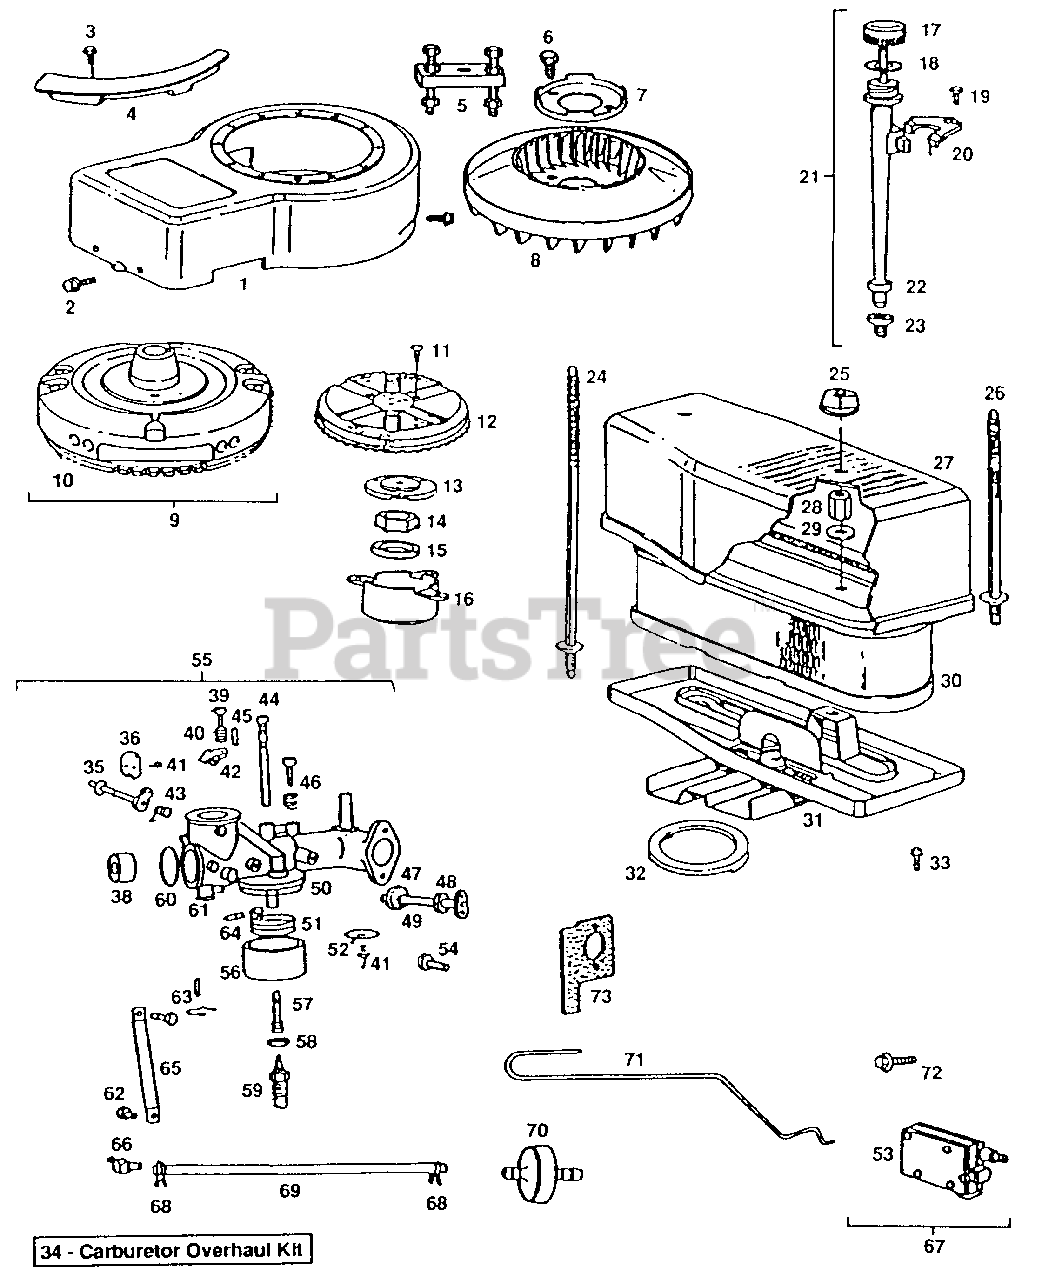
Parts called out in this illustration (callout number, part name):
1	Housing, Blower
2	Screw, Blower Housing Mounting Sem
3	Screw, Hex Hd.
4	Guard. Flywheel
5	Puller, Flywheel
6	Screw, Sem 3/4" Long
7	Retainer, Fan
8	Fan, Flywheel
9	Flywheel and Ring Gear Assy Magneto
10	Gear. Ring
11	Screw, Sem
12	Screen, Flush Rotating
14	Nut. Hex
15	Washer, Spring
16	Cup, Screen Mounting
17	Cap and Dipstick, Oil Filter
18	Seal, Oil Filler Cap
19	Screw, Clamp Mounting
20	Clamp, Oil Filler Tube
21	Fill Group, Oil
22	Tube. Oil Filler
23	Seal, Filler Tube
24	Stud, Air Cleaner
25	Knob. Air Cleaner
26	Stud. Air Cleaner
27	Cover. Air Cleaner
28	Nut, Air Cleaner Mtg.
29	Washer, Air Cleaner
30	Cartridge, Air Cleaner
31	Body, Air Cleaner
32	Gasket, Air Cleaner
33	Screw, Air Cleaner Sem
34	Carburetor Overhaul Lit
35	Washer, Choke Shaft
36	Valve, Choke
37	Shaft and Lever, Choke
38	Venture, Carburetor
39	Screw, Machine Fit Hd. 8-32 x 5/8"
40	Spring, Throttle Adjustment
41	Screw, Throttle and Choke Valve Mtg Sem
42	Stop, Throttle
43	Spring, Choke Return
44	Nozzle, Carburetor
45	Pin, Throttle Stop
46	Valve Assembly, Carburetor Idle
47	Washer, Throttle Shaft Seal (Foam)
48	Seal, Throttle Shaft
49	Shaft and Lever, Throttle
50	Gasket, Flat Bowl
51	Float, Carburetor
52	Valve, Throttle
53	Pump, Impulse
54	Screw, Carburetor
55	Carburetor Assembly
56	Bowl, Float
57	Screw, Nozzle
58	Washer, Float Bowl
59	Valve, Needle
60	Plug. Welch
61	Body Assembly, Carburetor
62	Screw, Carburetor
63	Valve, Fuel Inlet
64	Pin, Float Hinge
65	Bracket, Carburetor
66	Connector, Fuel Pipe
67	Repair Kit, Pump
68	Clamp, Fuel Pipe
69	Fuel Line (11" Long)
70	Filter, Fuel (In Fuel Line)
71	Link, Choke
72	Screw, Sem
73	Gasket, Carburetor Mounting
